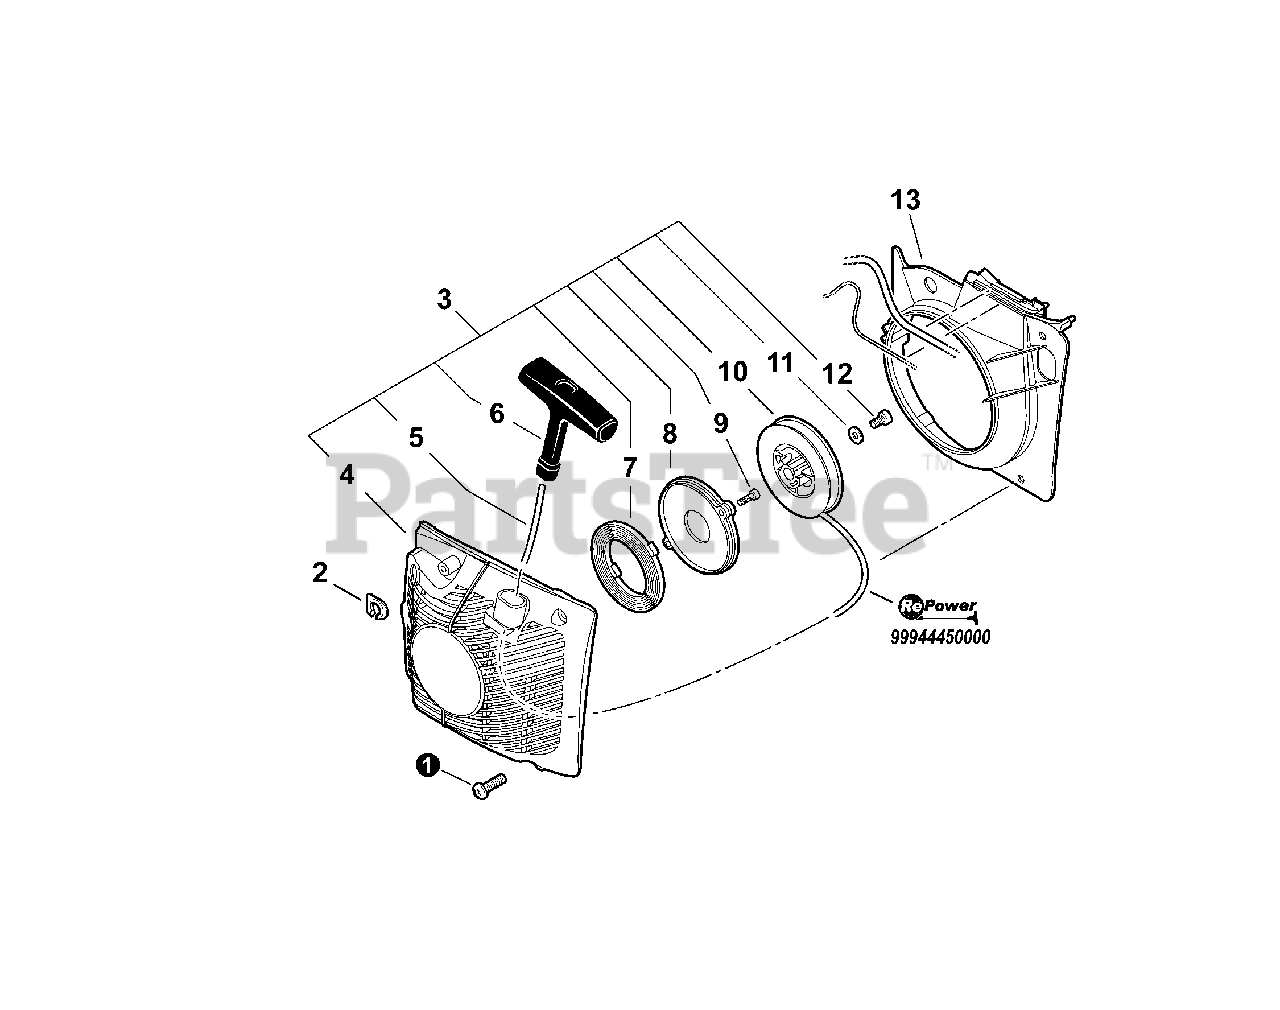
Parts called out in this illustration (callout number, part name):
1	BOLT, TORX 5
2	PLATE,EYE
3	STARTER ASY
4	STARTER CASE
6	GRIP, STARTER
7	SPRING, REWIND
8	PLATE, STARTER
9	BOLT, TORX 4
10	REEL, ROPE
12	BOLT, TORX 5
13	COVER,FAN
